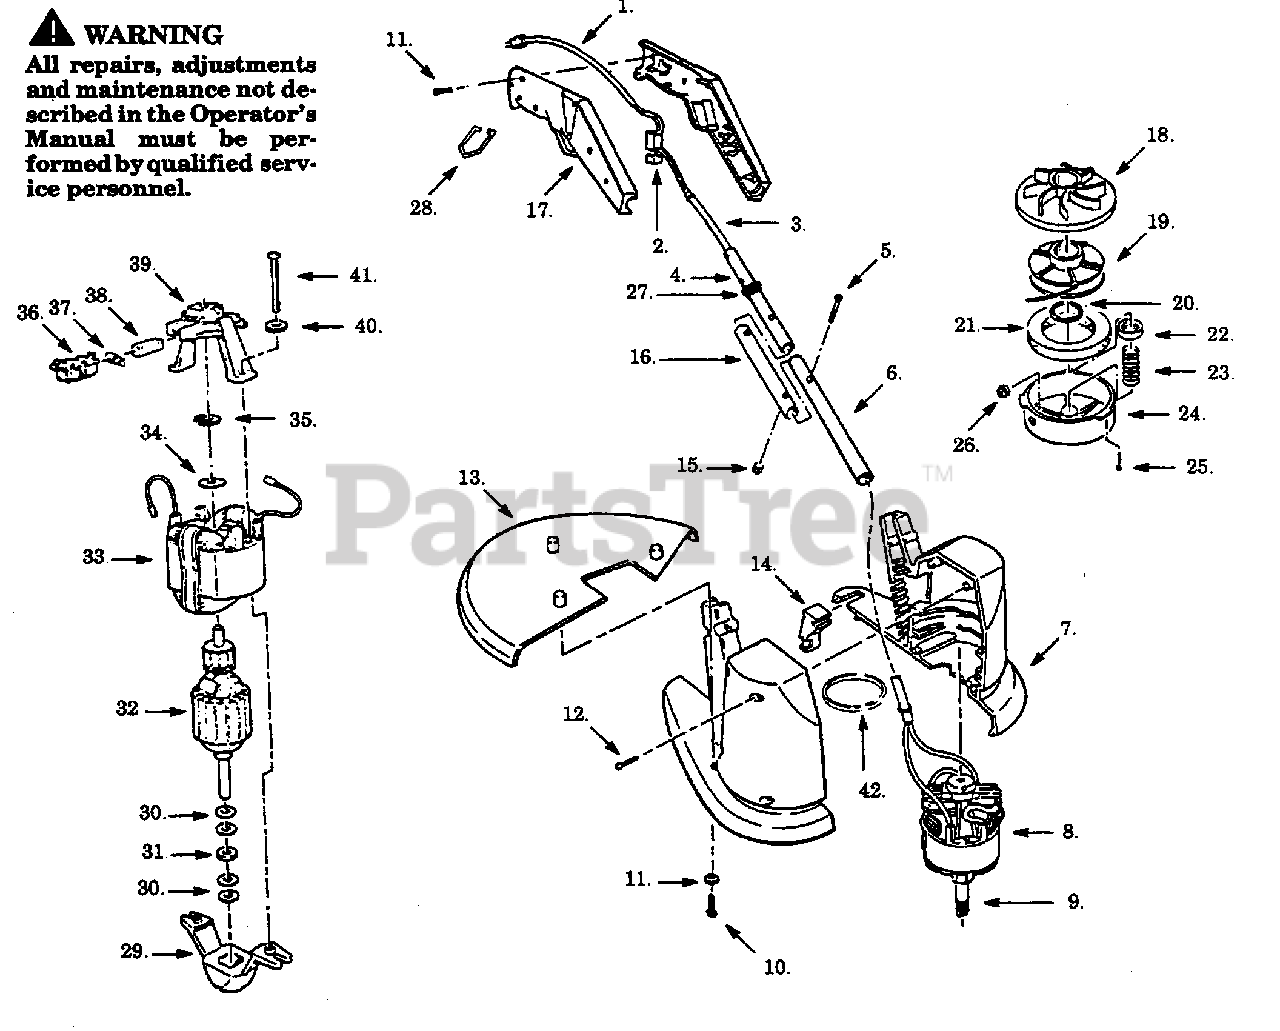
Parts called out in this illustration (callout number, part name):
1	Power Cord
4	Upper Tube
6	Lower Tube
7	R.H./L.H. Housing
9	Drive Adapter
14	Blade Retainer
16	Outer Tube
17	R.H./L.H. Handle
18	Rear Plate
19	Spool & Line
21	Foam Pad
22	Adapter Nut
24	Hub Ass'y.
25	Cotter Pin
29	Endbell (Drive)
32	Armature Ass'y.
33	Field Ass'y.
36	Brush Holder
37	Brush Spring
39	Endbell (Brush)
40	Lockwasher
42	Air Baffle
